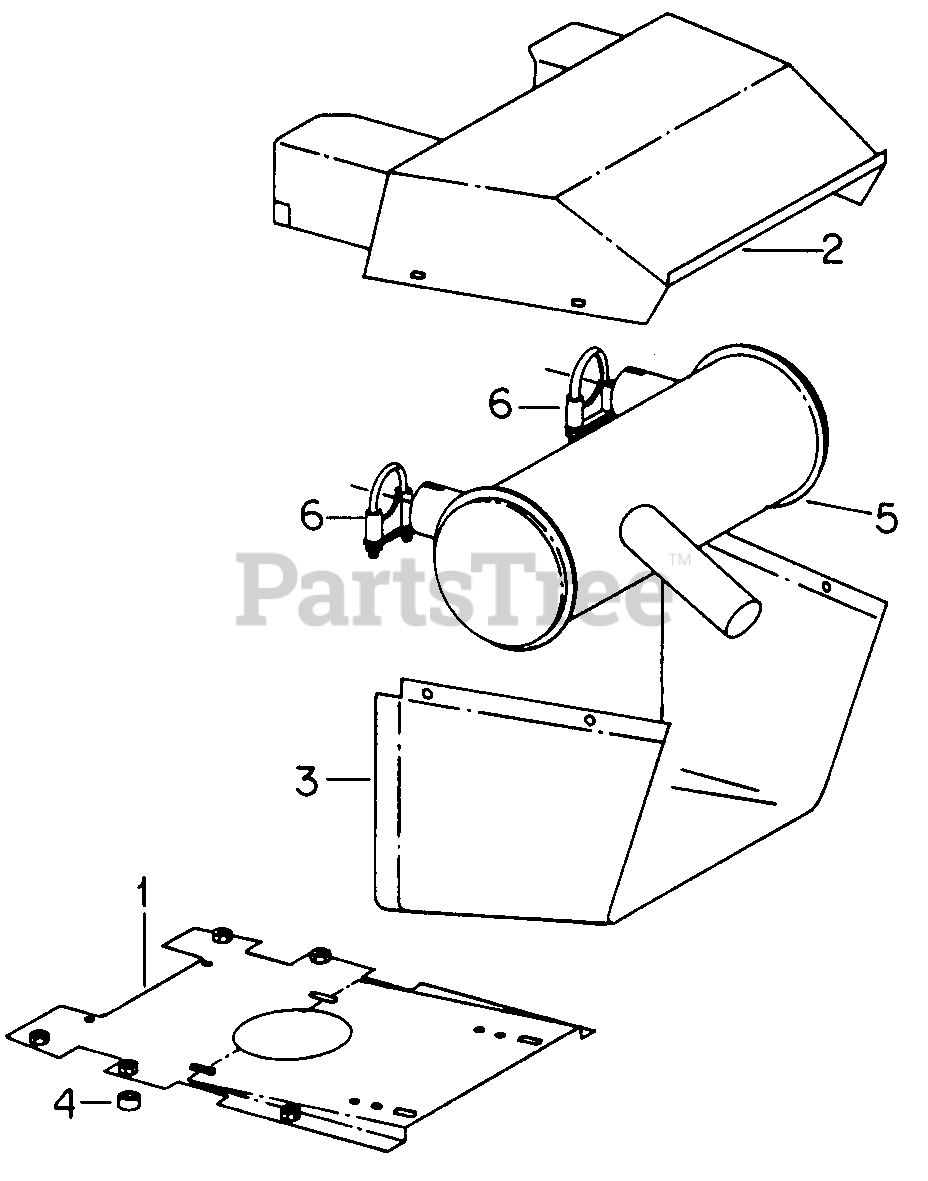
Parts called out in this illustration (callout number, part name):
1	Plate Assy, Eng Mtg
4	Spacer, 3/8 Pipe X .469
6	Clamp, Muffler
